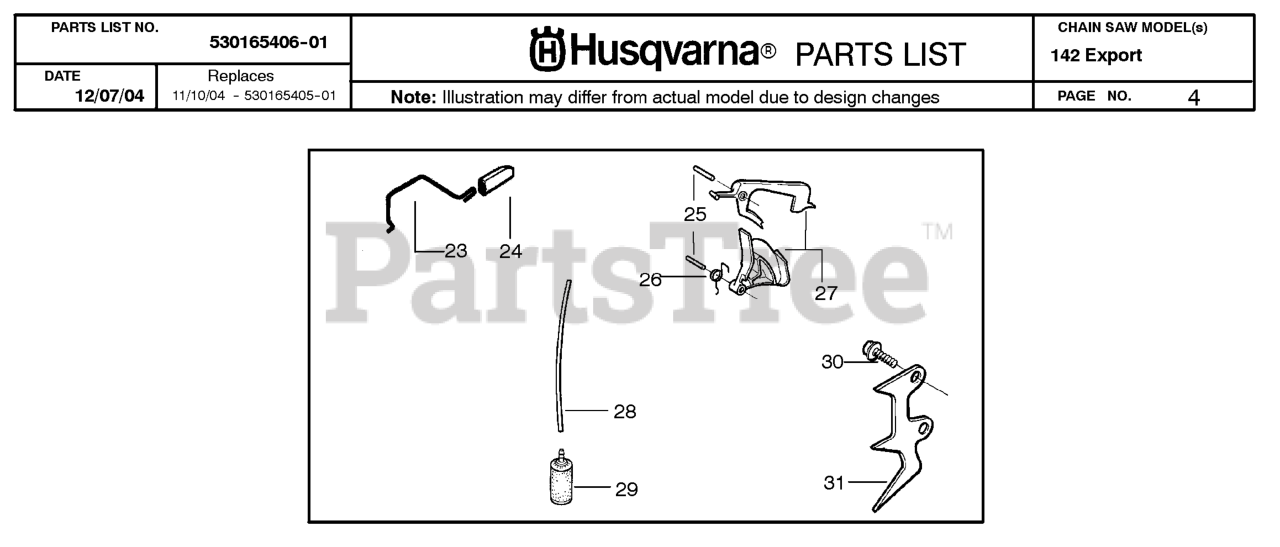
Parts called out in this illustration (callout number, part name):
23	THROTTLE SHAFT 36/41
24	THROTTLE ACTUATOR 36/41
25	PIN,TRIGGER 36/41
26	TRIGGER SPRING 36/41
27	THROTTLE TRIGGER-KIT
28	HOSE. FUEL
29	FUEL PICK-UP
31	SPIKE 36/41
